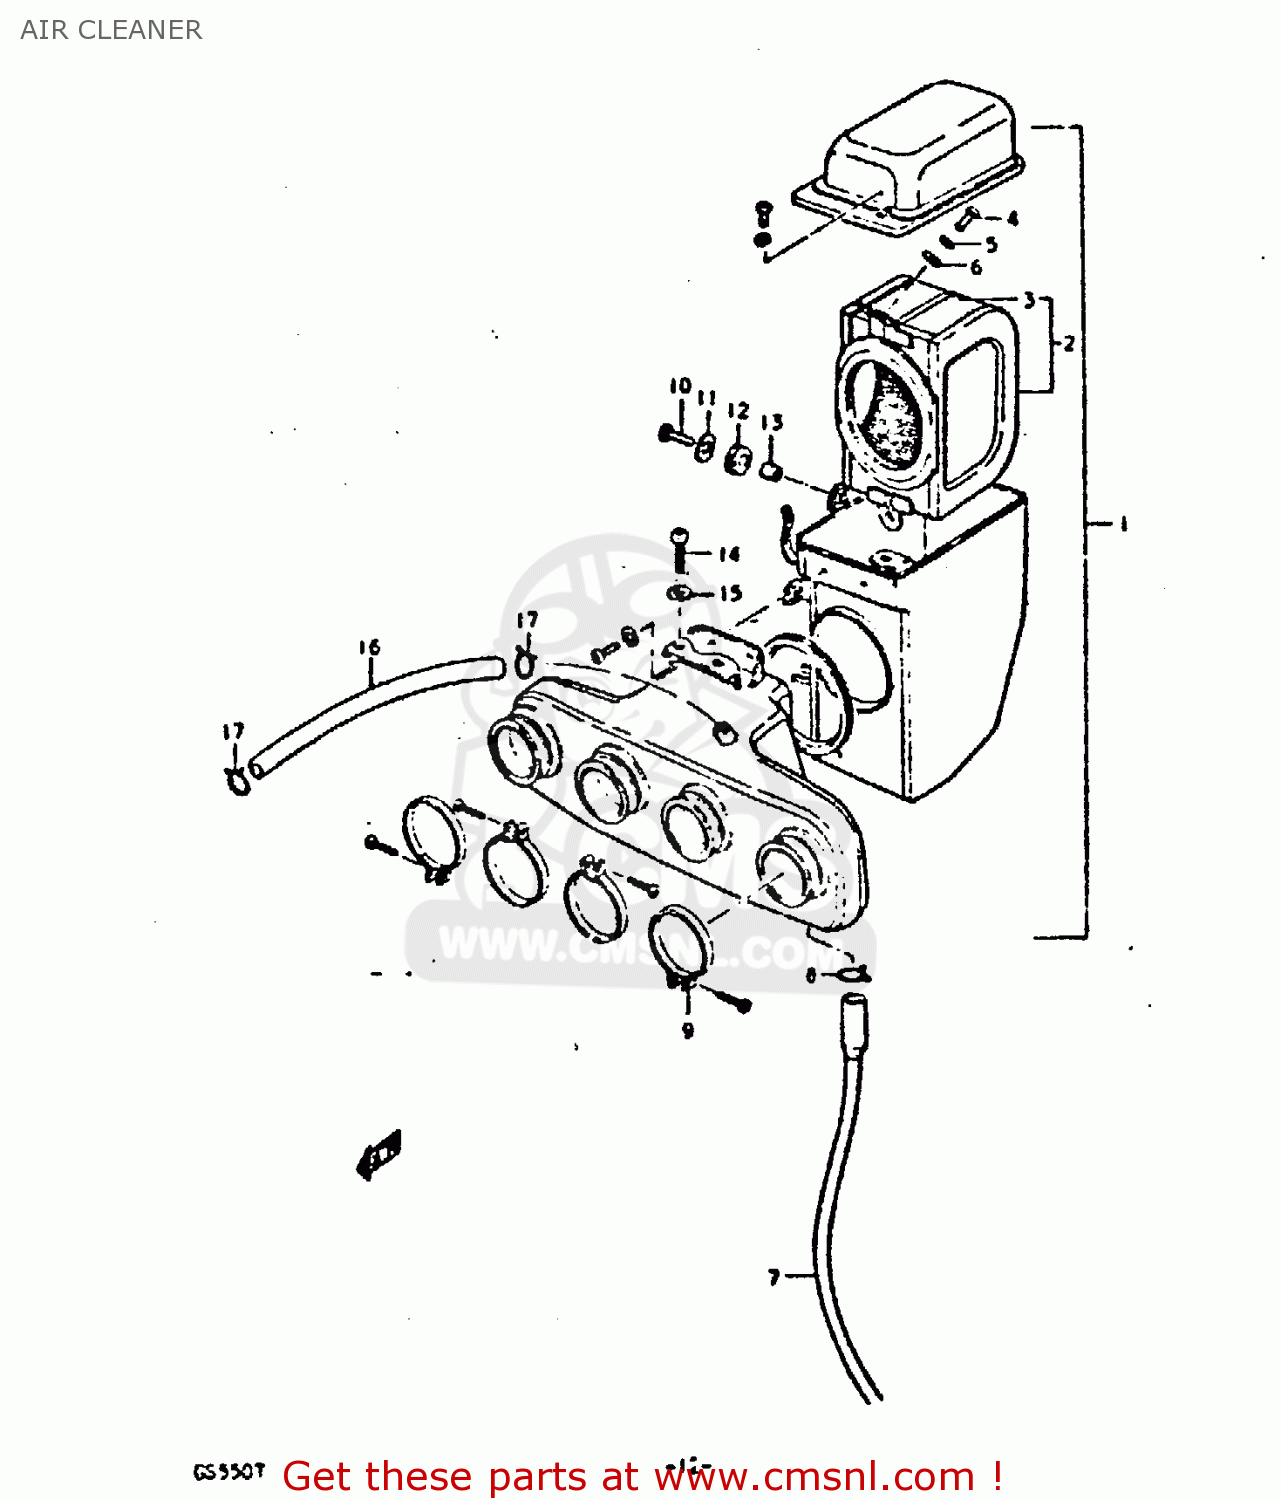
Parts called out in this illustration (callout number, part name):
1	CLEANER ASSY, AIR
2	FILTER ASSY
3	FILTER
4	SCREW
5	LOCK WASHER
6	WASHER
7	HOLDER,FILTER
8	CLIP
9	CLAMP
10	BOLT
11	WASHER
12	CUSHION
13	SPACER (6.1X9X9)
14	SCREW 6X12
15	WASHER
16	HOSE
17	CLIP
